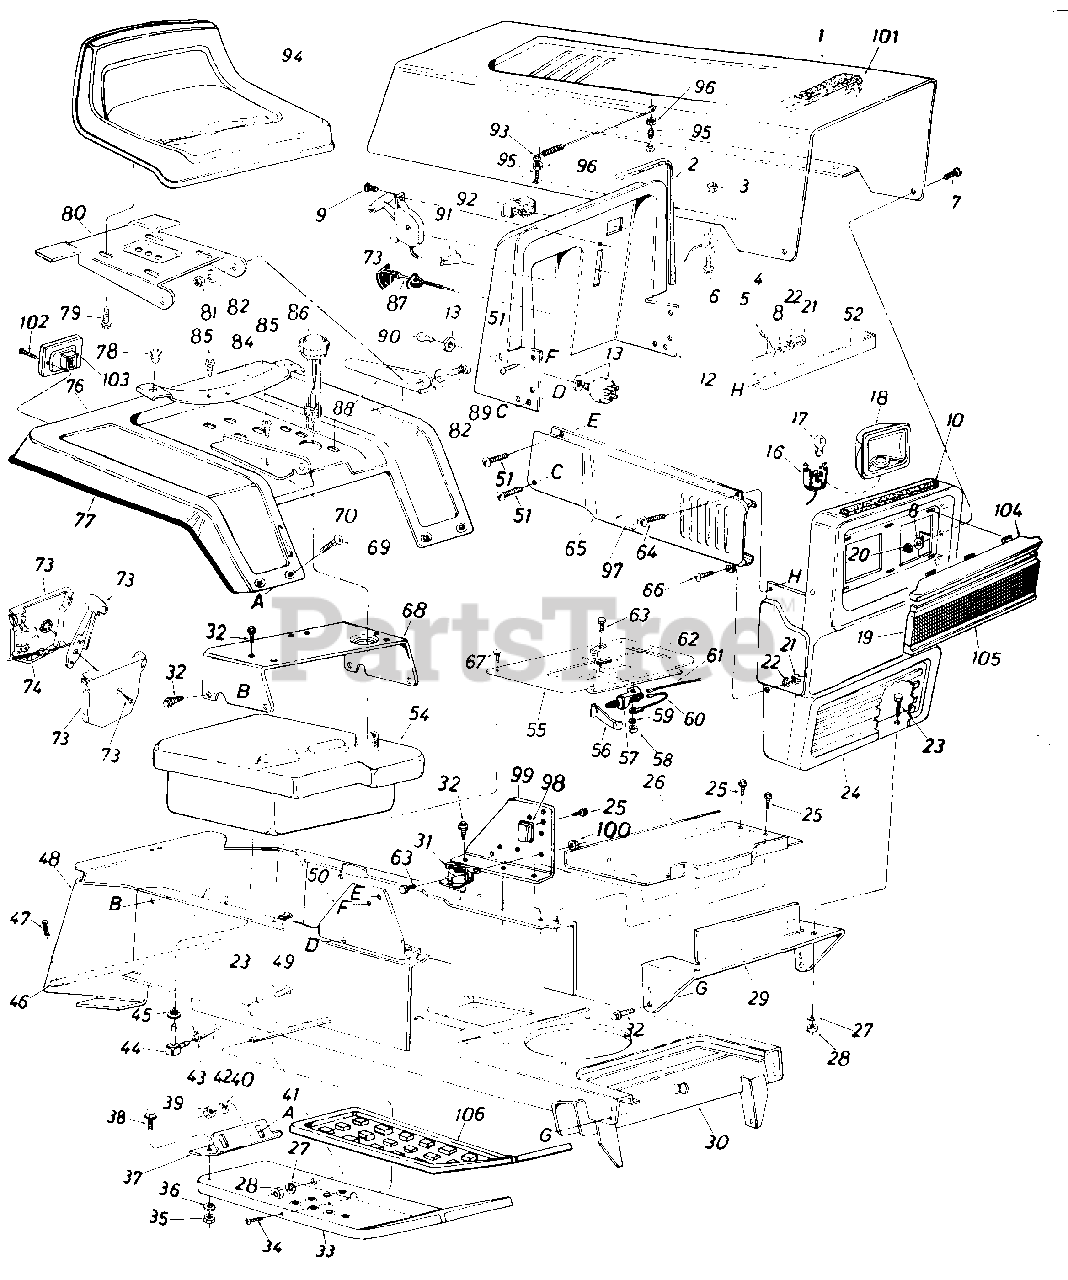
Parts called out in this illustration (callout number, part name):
1	Hood
2	Trim Strip 27" Lg.
3	Fl-Wash. .20" I.D. x .41" O.D.
5	Hood Stop
6	Truss Hd. Mach. Scr. #10-24 x.50" Lg.
7	Hex Bolt 1/4-20 x .62" Lg.
8	Fl-Wash. 1/4" I.D.
9	Truss Mach. AB-Tap Scr. #10 x .50" Lg.
10	Foam Strip 3/8" x 1" x 14"
12	Dash Ass'y.
13	Ignition Switch
16	Socket
17	Lamp
18	Headlight Housing
19	Headlight Bezel
20	Hex L-Nut 1/4-20 Thd.
21	Hex Nut 1/4-20 Thd.
22	L-Wash. 1/4" I.D.
23	Hex Bolt 5/16-18 x .75" Lg.
24	Grille
25	Hex Wash. Hd. Scr. 1/4" x .50" Lg.
26	Battery Plate
27	L-Wash. 5/16" I.D.
28	Hex Nut 5/16-18 Thd.
29	Grille Mounting Bracket
30	Lower Frame Ass'y.
31	Solenoid
32	Hex Thd. Rolling Scr. 5/16-24 x .75" Lg.
33	Running Board R.H.
34	Truss Mach. Scr. 5/16-18 x .75" Lg.
35	Hex Nut 5/16-18 Thd.
36	Bell-Wash. .34" I.D. x .87" O.D.
39	Hex Nut 1/4-20 Thd.
40	L-Wash. 1/4" I.D.
41	Running Board Rod
42	Fuel Line 40" Lg.
43	Hose Clamp 3/8"
44	90ø Nipple
45	Bushing
46	Hitch Rod
47	Internal Cotterpin
48	Hitch Plate
49	Speed Nut
50	Dash Support Brkt. R.H.
51	Hex Wash. Hd. Tap Scr. 1/4 x .75" Lg.
52	Tie Strap
54	Fuel Tank
55	Transmission Cover Ass'y.
56	Switch Actuator Spring Lever
57	Safety Switch
58	Hex Nut 1/4-20 Thd.
59	L-Wash. 1/4" I.D.
60	Electric Wire
61	Reverse Lockout Wire Harness
62	Snap Bushing
63	Hex Bolt 1/4-20 x .50" Lg.
64	Truss Hd. Scr. 1/4-20 x .75" Lg.
65	Side Panel R.H.
66	Truss Mach. Scr. 1/4-20 x .50" Lg.
67	Truss Mach. "B" Tap Scr. #10 x .50" Lg.
68	Seat Mounting Channel
69	Carriage Bolt 1/4-20 x .50" Lg.
70	Seat Bracket R.H.
73	Throttle Control Box Ass'y.
74	Throttle Control Wire
76	Rear Fender
77	ITrim Strip 81"
78	Grommet
79	Hex Wash. Hd. AB-Tap Scr. 3/8 x .75" Lg.
80	Seat Pivot Bracket
81	Hex Cent. L-Nut 5/16-18 Thd.
82	Belleville Wash. .34" I.D. x .88" O.D.
84	Seat Spring
85	Hex Wash. Hd. Self-Tap Scr. 5/16-18 x .50" Lg.
86	Gas Cap w/Gauge
87	Choke Control Comp.
88	Seat Bracket L.H.
89	Hex Bolt 5/16-18 x .75" Lg.
90	Ignition Key
91	Light Switch
92	Ammeter
93	Hood Spring
94	Seat Ass'y.
95	Hex Screw #10-24 x 1.0" Lg.
97	Rubber Strip 1/2" Sq. X 2-1/2 " Lg.
98	Circuit Breaker
99	Dash Support Brkt. L.H.
100	Hex Sems Nut 1/4-20 Thd.
101	PVC Foam
102	Truss Hd. AB-Tap Scr. #6 x .62" Lg.
103	Taillight
104	Upper Frame For Bezel
105	Lower Frame For Bezel
106	Foot Pads
